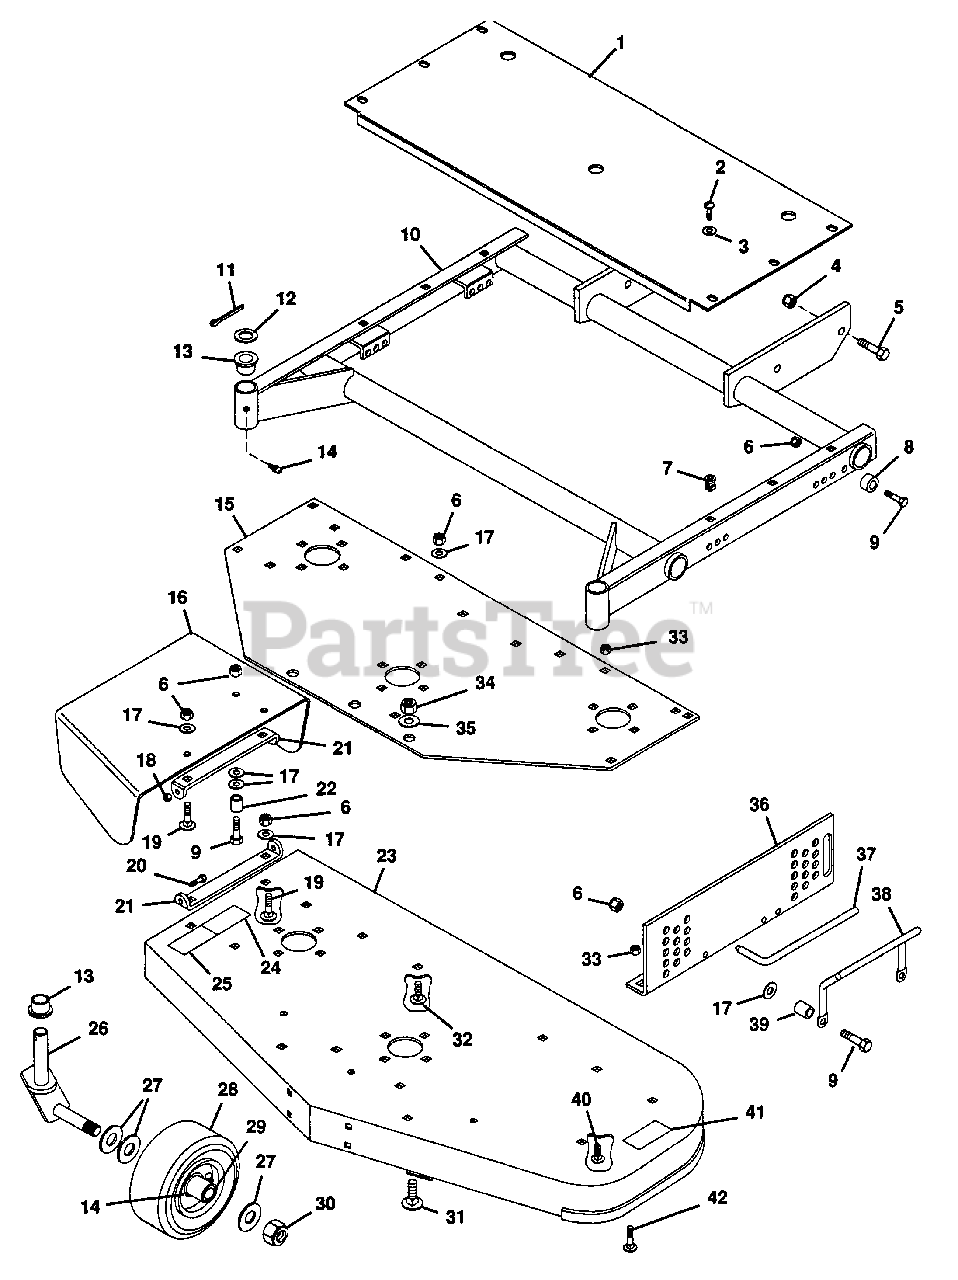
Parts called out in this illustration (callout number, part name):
1	Guard, 50" Mower Belt
2	Screw, 1/4-20x.50 Self Tapping
3	Washer, Flat .281x.625x.065
4	Nut, Lock 5/8-11
5	Bolt, Hex 5/8-11x1.50
6	Nut, Lock 3/8-16
7	Grommet, Plastic
8	Bush., St. .391x.621x.676 Stl.
9	Bolt, Hex 3/8-16x1.50
10	Weldment, Mower Frame
11	Pin, Cotter .187x1.50
12	Race, Bearing Thrust
13	Bush., Flange Nylon
14	Fitting, Lube 1/4-28
15	Plate, Support
16	Shield, Safety Ext. 50" Mower
17	Washer, Flat .406x.812x.065
18	Nut, Lock 1/4-20
19	Bolt, 3/8-16x1.00 Rd Hd Sq Nk
20	Bolt, Hex 1/4-20x.875
21	Bracket, Chute
22	Stop, Chute
23	Weldment, 50" Mower Fabricated
24	Decal, Danger Hand
25	Decal, Warning Eye
26	Weldment, Caster Fork
27	Washer, Flat .812x1.496x.134
28	Wheel, Gauge
29	Bearing, Gauge Wheel
30	Nut, Lock 3/4-10
31	Bolt, 1/2-13x1.00 Rd Hd Sq Nk
32	Bolt, Carriage 3/8-16x.75
33	Nut, Lock 5/16-18
34	Nut, Lock 1/2-13
35	Washer, Flat .531x1.250x.100
36	Bracket, Mower Side Support L.H.
36	Bracket, Mower Side Support R.H.
37	Pin, Mower Locking
38	Handle
39	Bushing
40	Bolt, 5/16-18x.625 Rd Hd Sq Nk
41	Decal, Danger Foot
42	Bolt, Carriage 5/16-18x1.00
